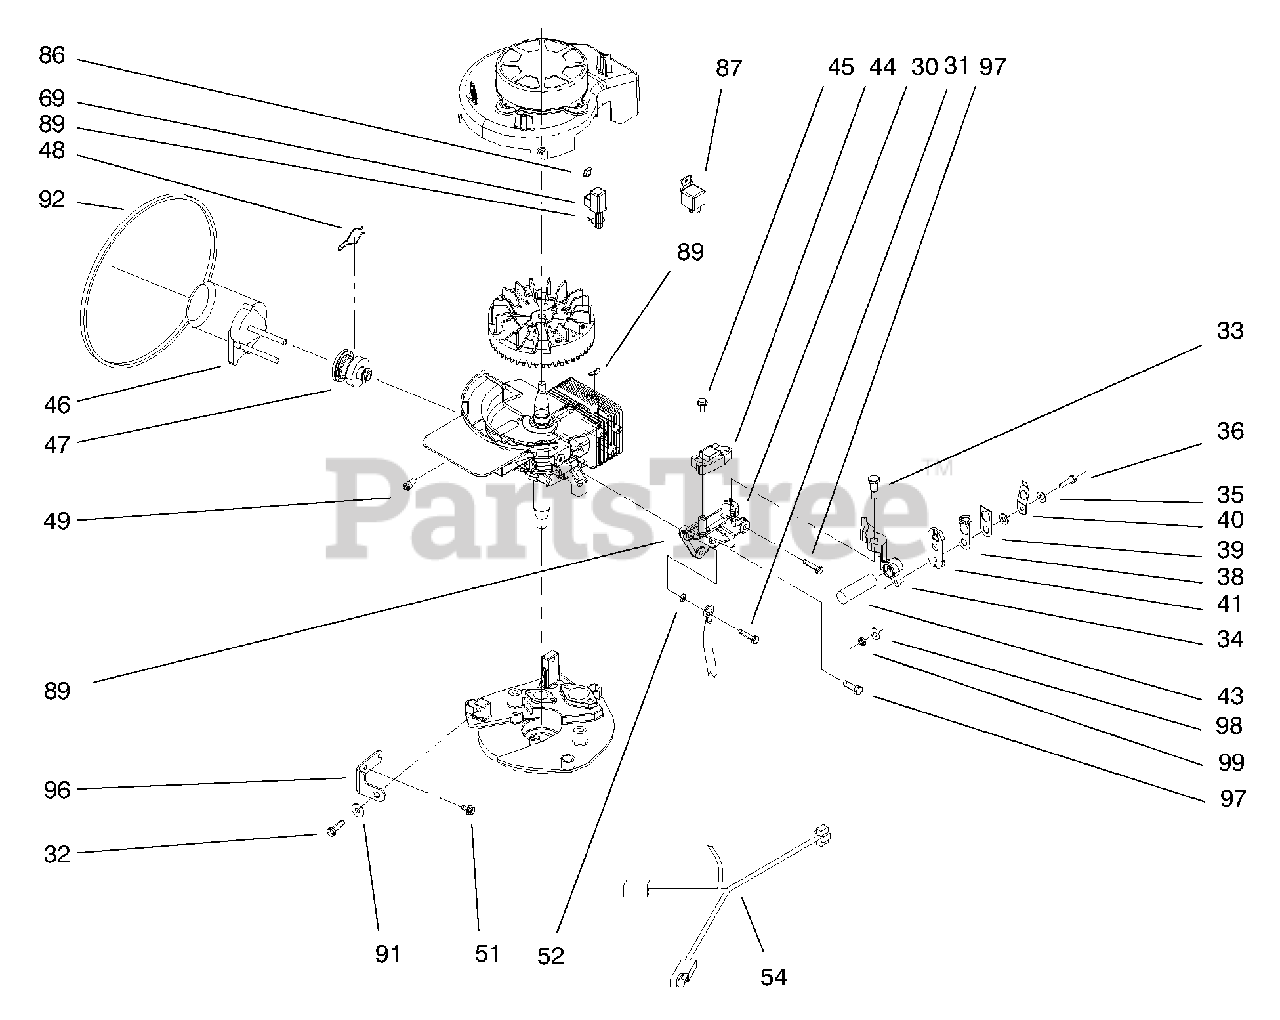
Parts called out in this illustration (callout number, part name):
30	Bracket Alt & Brake Mtg
31	Screw-Cap
32	Screw-HHF
34	Assy-Brake w/ Pad
35	Washer
36	Screw-HH
38	Plate-Contact
41	ASM-Case
42	Wire Lead
43	Spring-Brake
44	Alternator Assembly
45	Screw-HWH
46	ASM-Starter
47	Pinion-Spring & Clutch
48	Spring-Drag
49	Screw-Socket Head
51	Screw
52	Washer-Lock
54	Wire Harness
68	Sealer-Loctite
69	Cup Assembly
89	Tie Strap
91	Washer-Lock
92	Tie-Cable
96	Bracket-Elect.
97	Screw-HH
98	Washer-Lk
99	Locknut
